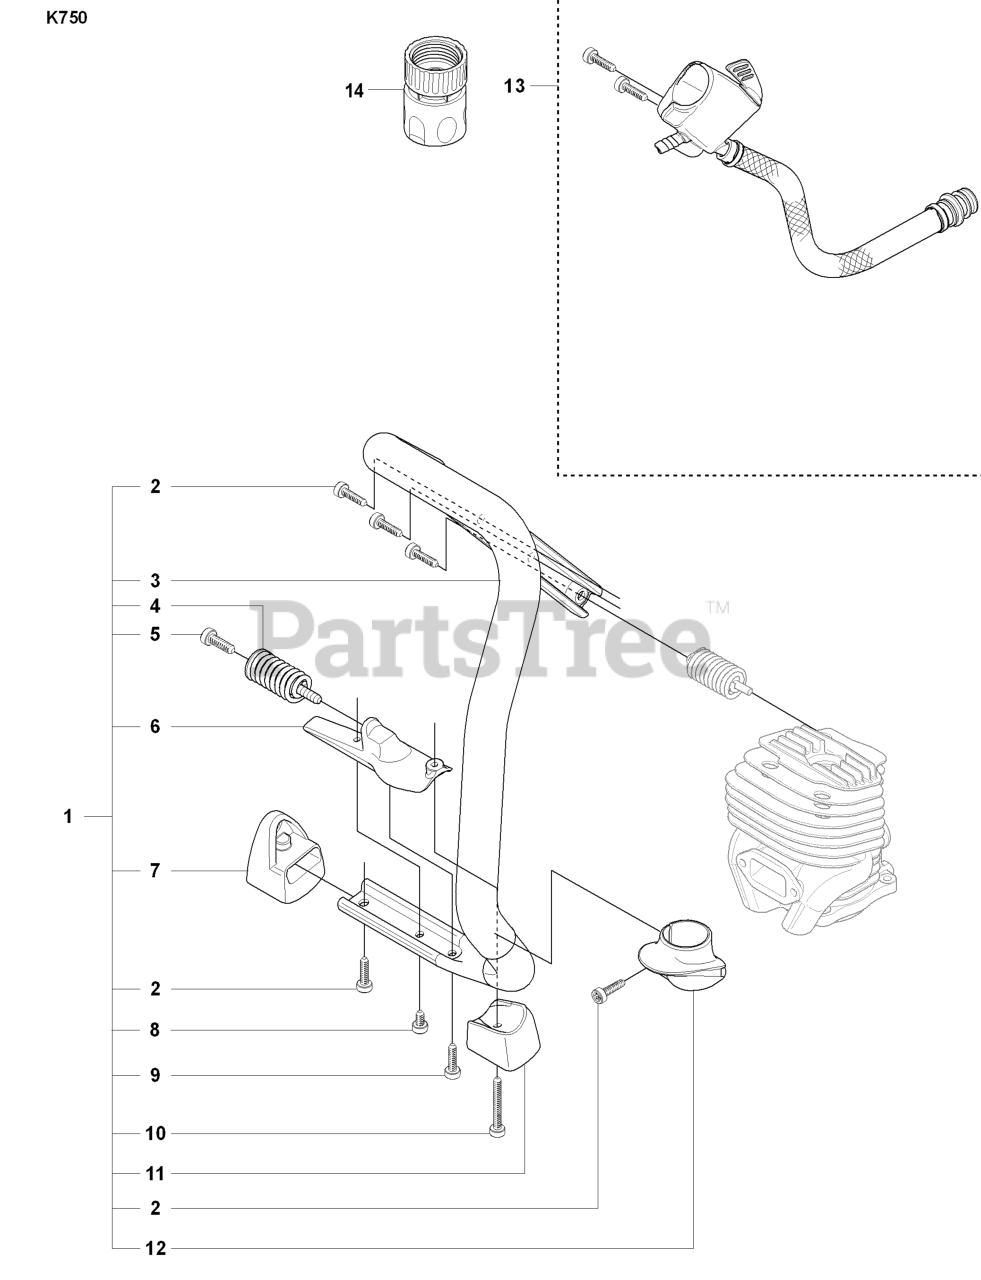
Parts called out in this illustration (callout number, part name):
1	%HANDLE
3	FRONT HANDLE
4	%VIBRATION ABSORBER
6	%SPRING RETAINER
7	GROUND SUPPORT
11	GROUND SUPPORT
13	RP HOSE
14	FEMALE QUICK COUPLER
